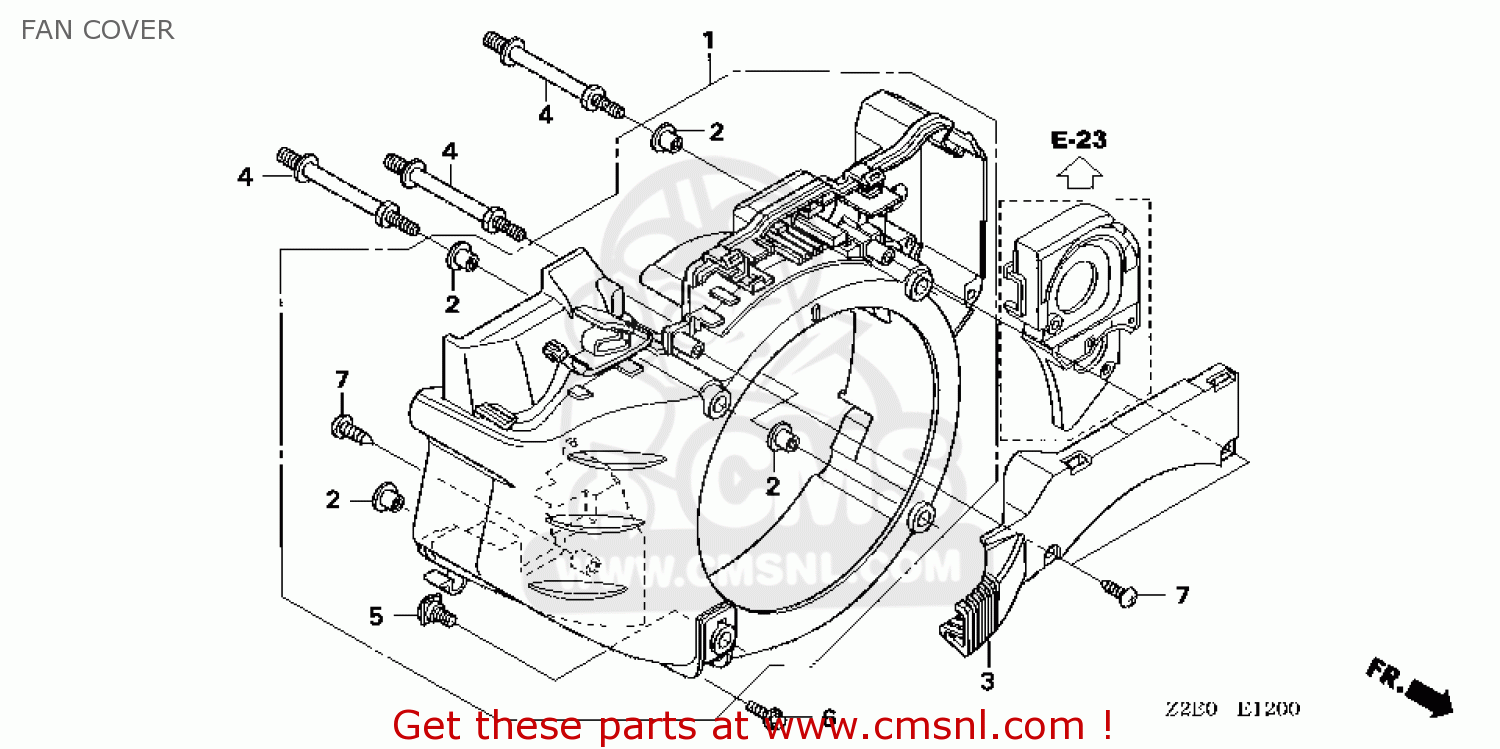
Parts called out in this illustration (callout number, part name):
001	COVER COMP,FAN
002	COLLAR,FAN/C
003	COVER,ELEC PARTS
004	BOLT,STUD(FAN/C)
005	BOLT,SPECIAL 6MM
006	BOLT,FLANGE, 6X25
007	SCREW,TAPPING,(PO
